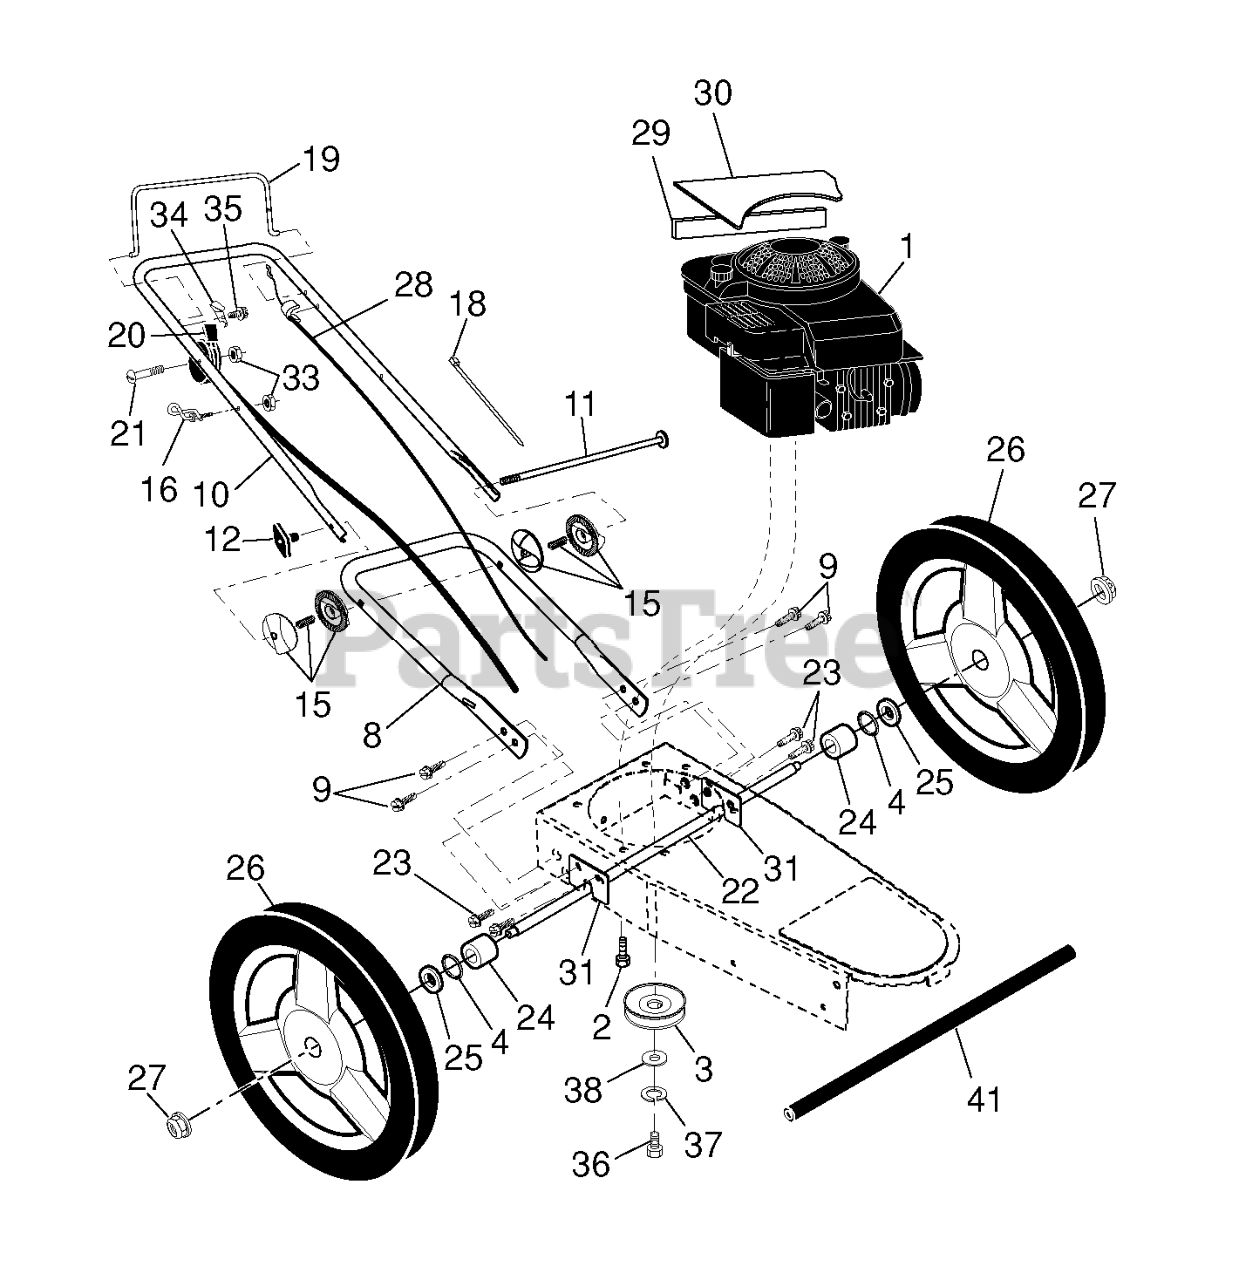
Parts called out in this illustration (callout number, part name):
2	BOLT 3/8-16X1-1/8
3	PULLEY, ENGINE
4	O-RING..070X.487.NEOPRENE
8	HANDLE.LOWER.STRING.TRIMMER.GR
9	BOLT.HEX.HD.WASHER.5/16-18X.75
10	HANDLE.UP.STRING.TRIMMER.GREY
11	BOLT.HANDLE.WHEELED.TRIMMER
12	KNOB.WING.PLASTIC.BLACK
15	ADJSTR.ASSEM.HANDLE.WHLD.TRIMM
16	RB GUIDE.ROPE.STD.BLK.ZIN WSL
18	TIE GUIDE
19	BAIL.SPINDLE.ENGAGE.BLACK
20	RP CONTROL.THRO.S-TRM.SNPIN.BS
21	SCREW.PAN.HEAD
22	AXLE SHAFT ASSEMBLY
23	BOLT.HEX.HD.WASHER.5/16-18X.75
24	SPACER.AXLE.STRING.TRIMMER
25	WASHER.FLAT.1/2
26	WHEEL.12X1.75.CF.H3SPKRAD3
27	NUT.HEX.FLANGE.3/8-16.LOCKNUT
28	CONTROL.DRIVE.TRIMMER.WHEELED
29	DECAL, WARNING
30	DECAL, WARNING
31	BRACKET, AXLE
33	NUT
34	BRACKET.UPSTOP.RT
36	SCREW, HEX HD 3/8-24 X 1-3/8
37	LOCKWASHER
38	WASHER,HARDEN
41	TUBE.AXLE.TRIMMER.BLACK
